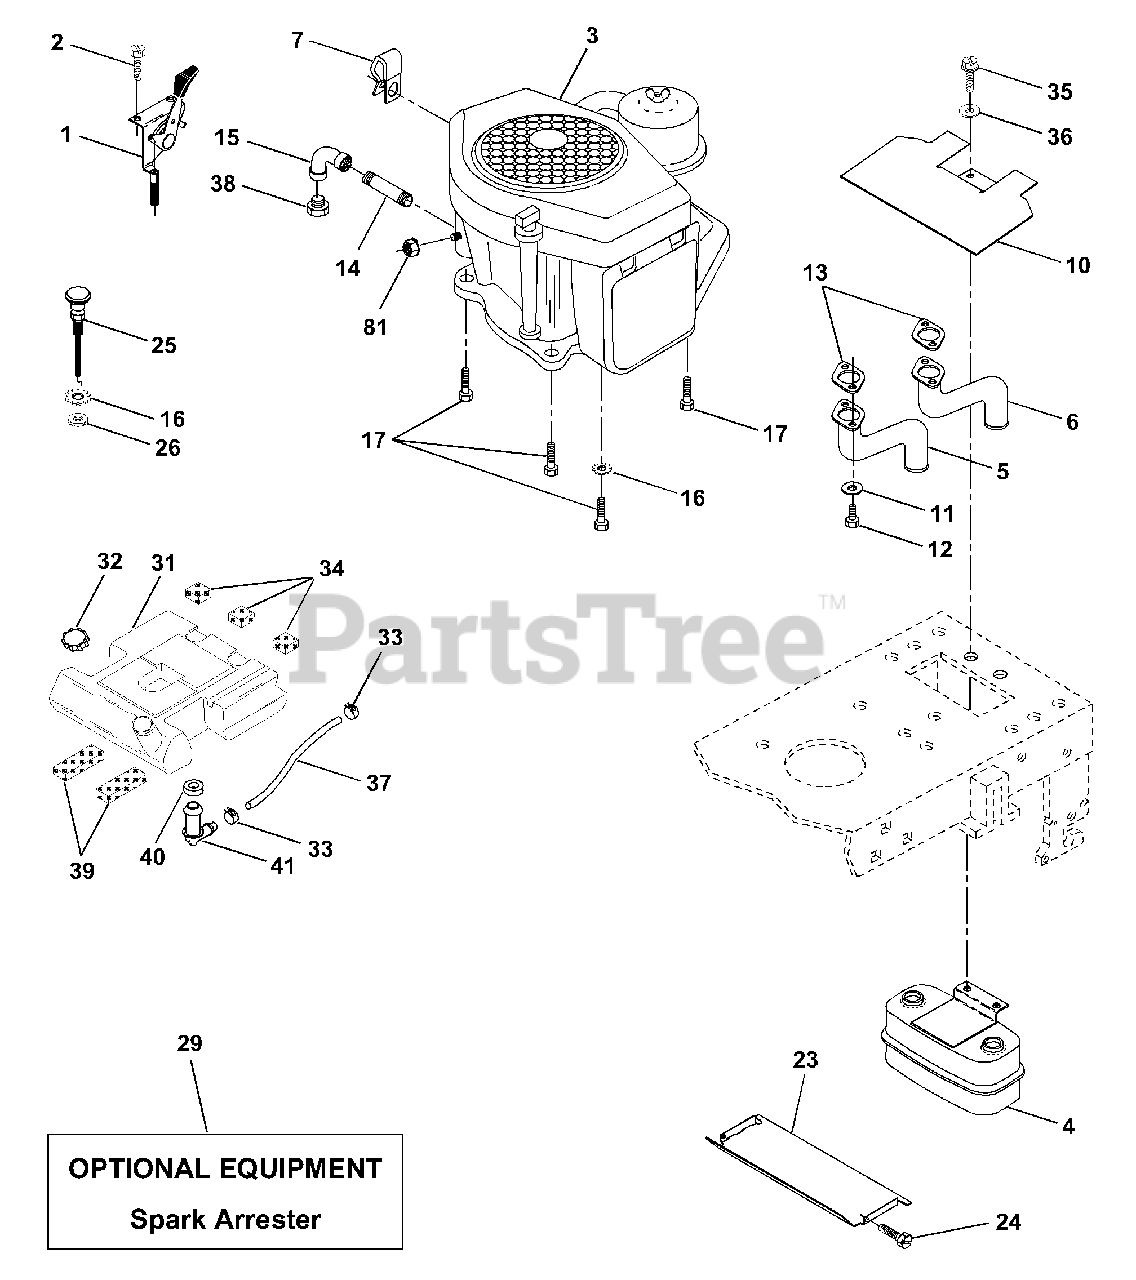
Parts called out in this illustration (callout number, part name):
1	Control Throt LH Blk 180 46"
2	Screw Hex Thd Cut 1/4-20x5/8 T
4	Muffler Asm Twin Lo-Tone
5	Pipe Exhaust CV18/20 LH
6	Pipe Exhaust CV18/20 RH
7	Clip, Fuel Line
10	Shield Heat Muffler CV18/20
13	Muffler Gasket
14	Nipple Pipe 3/8 Npt X 4-1/2"
15	Elbow Std 90 Degree 3/8-18 Npt
16	Washer Lock Ext Tooth 3/8
17	Screw Thdrol 3/8-16 x 1-1/2
23	Shield Heat Browning LT/YT
24	Screw Tap Hex #10-24unc X 1/2
25	Choke Control 37"
26	Nut, Fin Hex 3/8-24 Unf
29	Kit Spark Arrestor (Flat Scrn)
31	Tank Fuel 3 50 Rear
32	Cap Asm Fuel Top N/Lany Vented
33	Clamp Hose Blk
34	Pad, Spacer
35	Screw Thdrol 5/16-18 x 3/4
36	Washer 13/32 x 1-1/4 x 12 Ga.
37	Line Fuel 7.5
38	Plug Oil Drain
39	Pad, Idler
40	Bushing
41	Stem Tank Fuel
81	Nut Flange 1/4-20 Starter Nut
